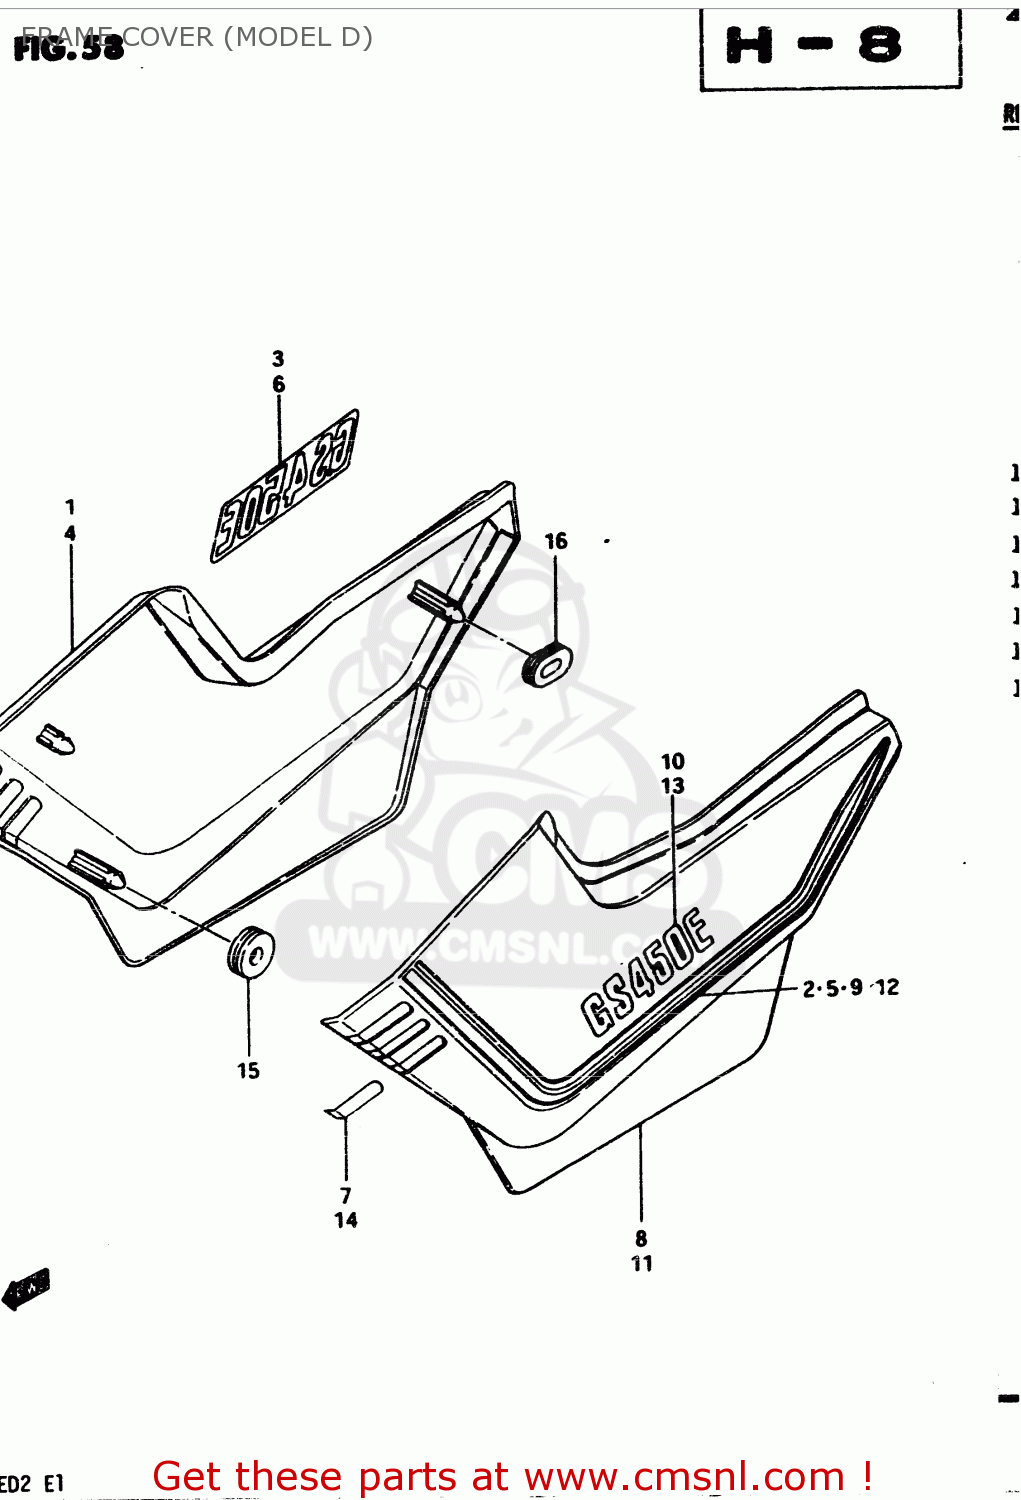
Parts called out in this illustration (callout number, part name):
1	COVER, FRAME RH (RED)
2	TAPE SET, FRAME COVER RH
3	EMBLEM,FRAME COVER
4	COVER, FRAME RH (SILVER)
5	TAPE SET, FRAME COVER RH
6	EMBLEM, LH
7	LABEL,FRAME COVER DENT
8	COVER, FRAME LH (RED)
9	TAPE SET, FRAME COVER LH
10	EMBLEM,FRAME COVER
11	COVER, FRAME LH (SILVER)
12	TAPE SET, FRAME COVER LH
13	EMBLEM, LH
14	LABEL,FRAME COVER
15	CUSHION
16	CUSHION
